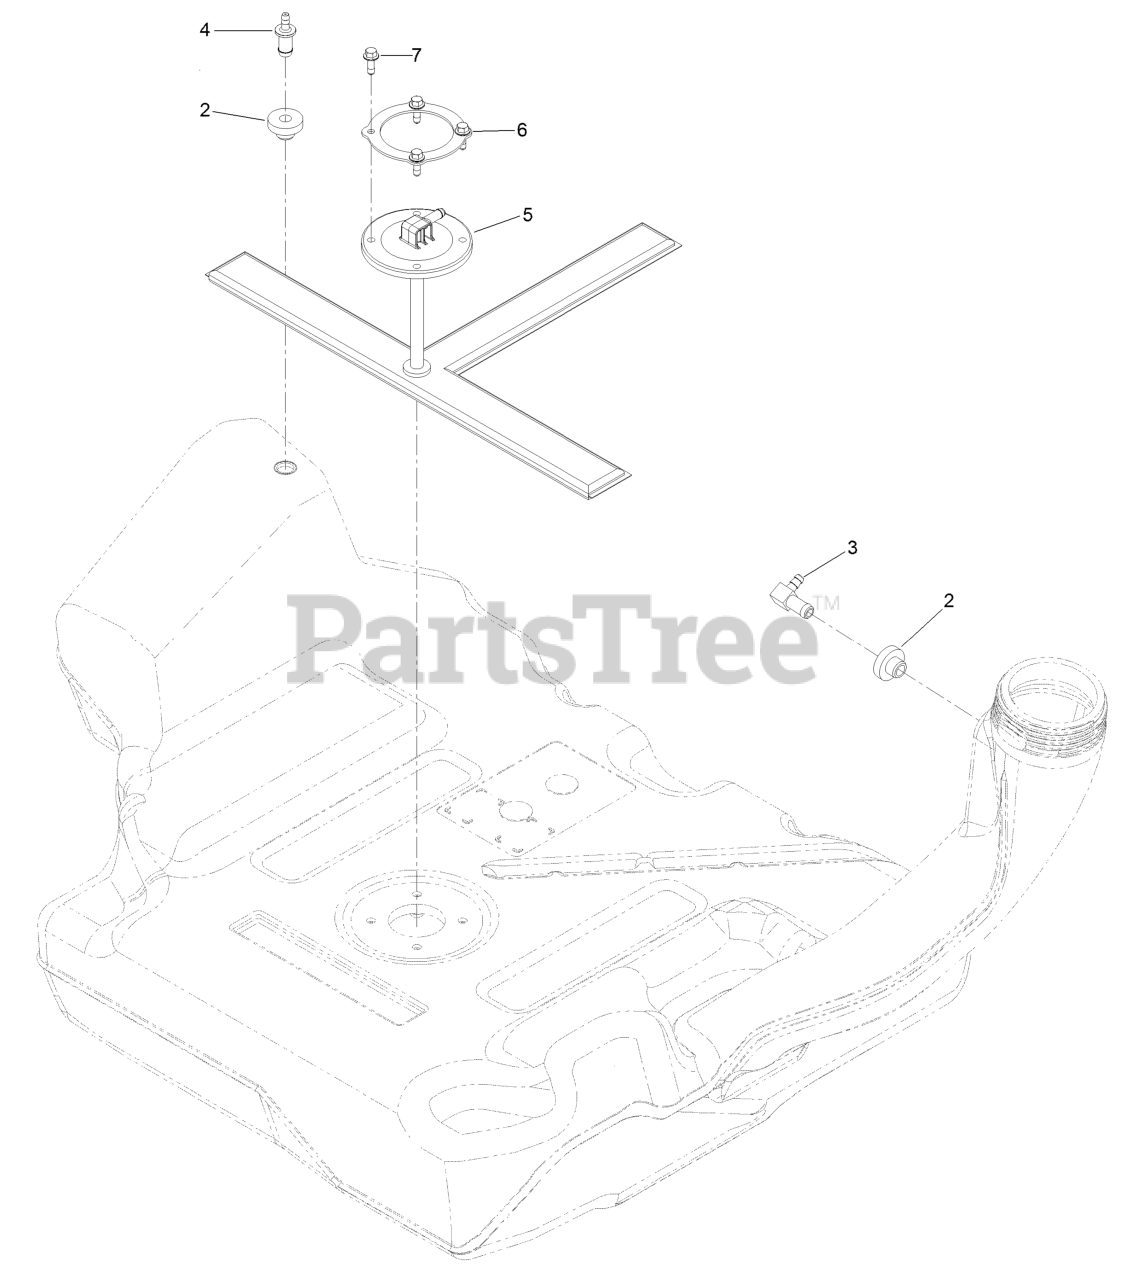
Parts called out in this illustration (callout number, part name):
2	Bushing
3	Fitting-90 DEG
4	Fitting-Orifice, Straight
5	Pickup-Fuel
6	Ring-Retainer
